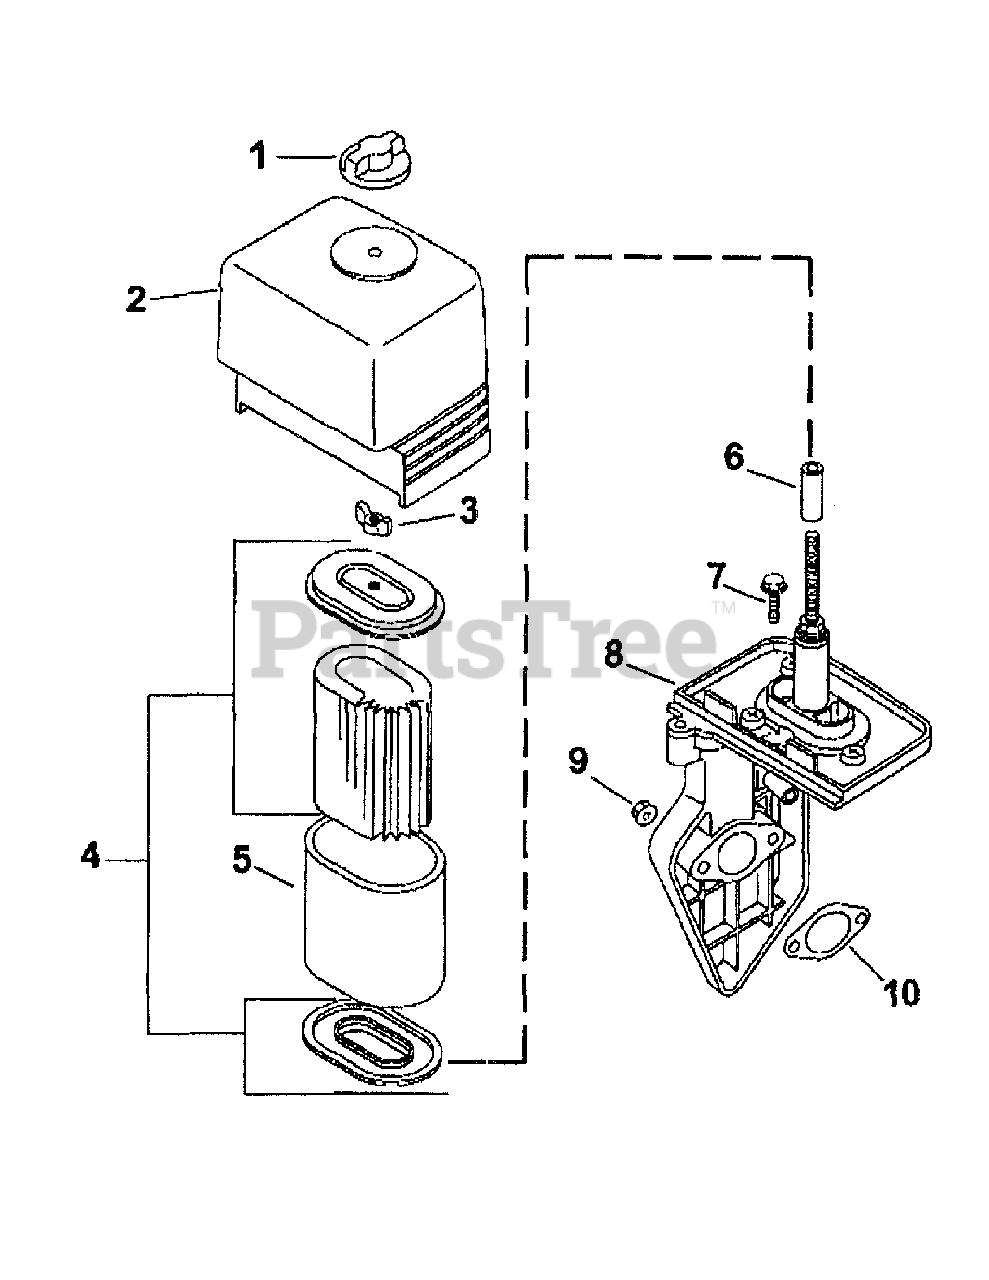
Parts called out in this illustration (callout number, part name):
1	Nut, Air Cleaner
2	Cover, Air Cleaner
3	Nut, Wing-Air Cleaner
4	Element, Air Cleaner
5	Element, Precleaner
6	Seal, Air Cleaner
8	Base, Air Cleaner
9	Nut, Air Cleaner
10	Gasket, Air Cleaner
